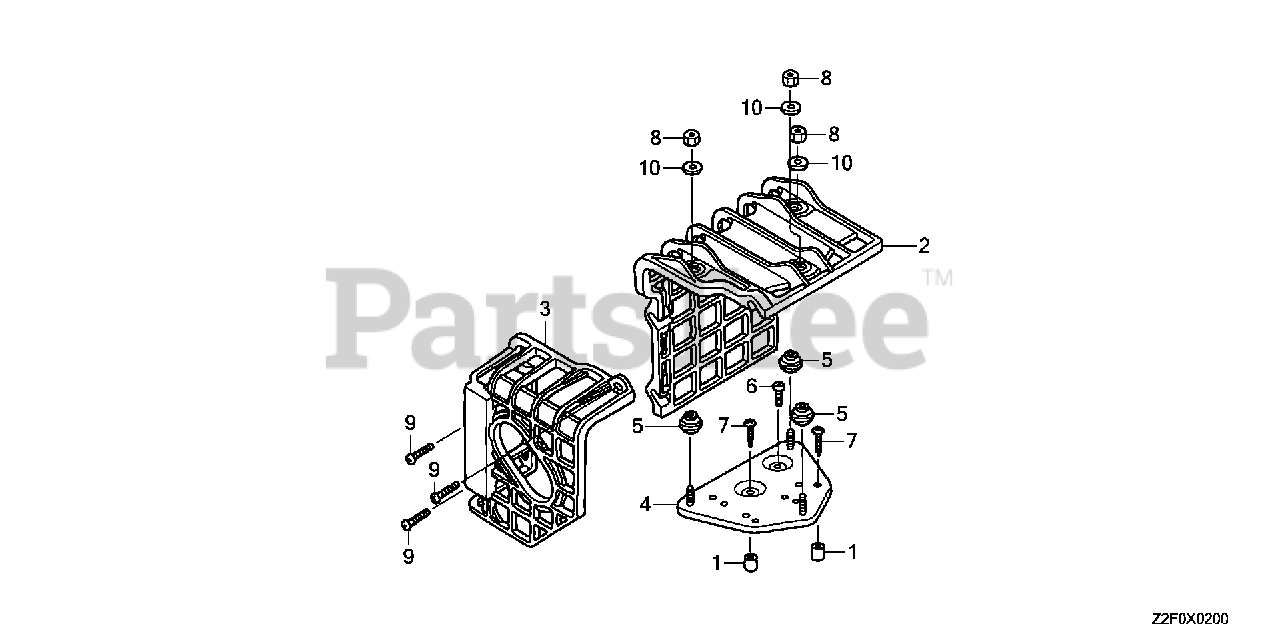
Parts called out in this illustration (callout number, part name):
1	COLLAR, AIR CLEANER HOUSING
2	COVER, MUFFLER
3	COVER, RR. MUFFLER
4	BASE, MUFFLER COVER
5	SPACER, MUFFLER COVER
6	SCREW, TAPPING (5X8)
7	SCREW, TAPPING (5X25)
8	NUT, HEX. (5MM)
9	SCREW-WASHER (6X20)
10	WASHER, PLAIN (5MM)
